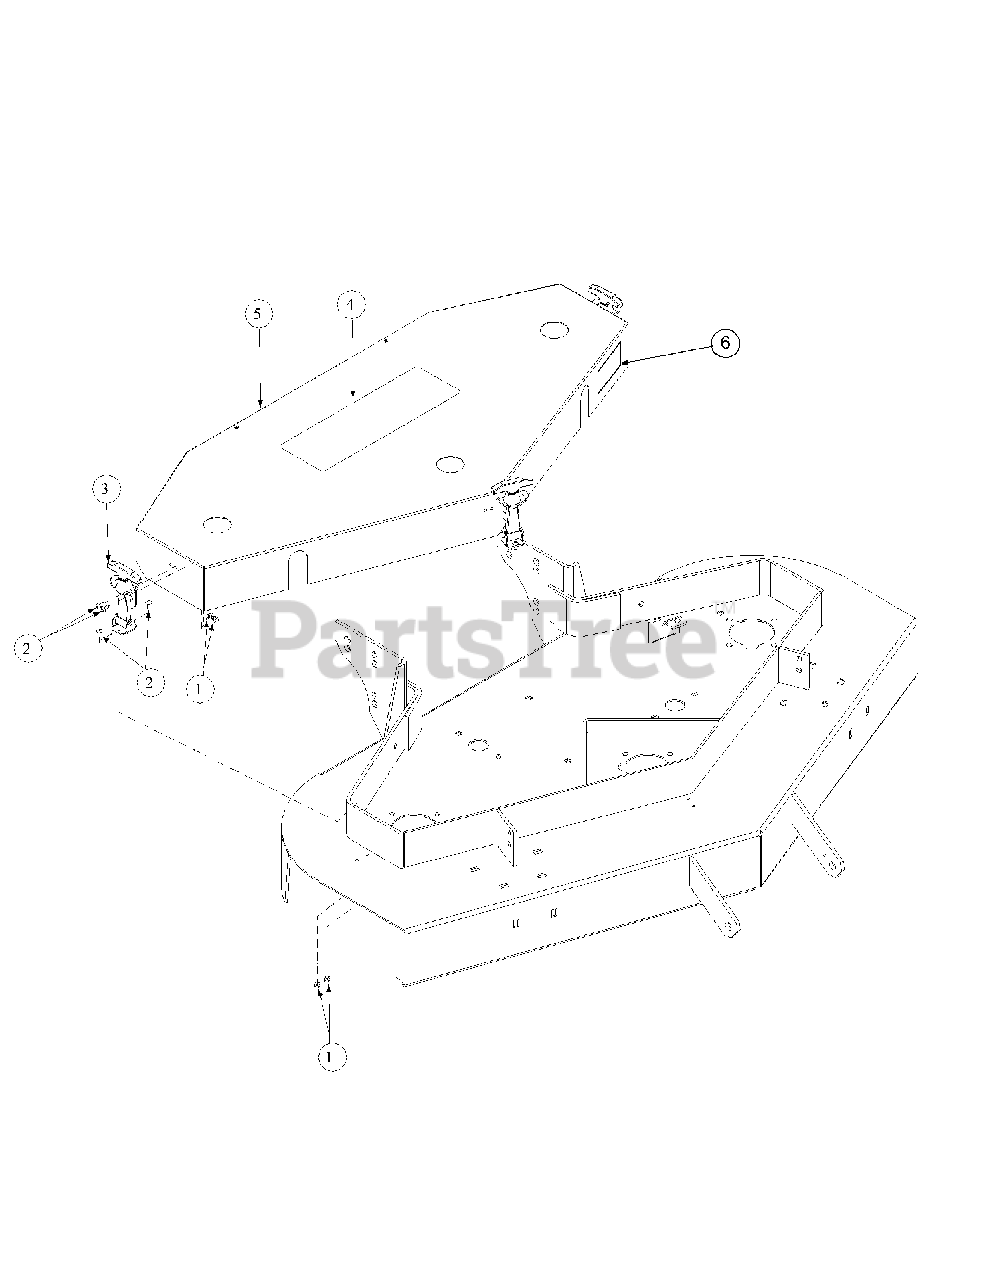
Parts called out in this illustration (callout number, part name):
1	Lock Nut, Nylon Insert, #10-24
2	Machine Screw, 10-24 x 1/2
3	Rubber Hood Latch
4	Label, Commercial Mower
5	Cover Assembly, Belt, 52"
6	Label, G1752
